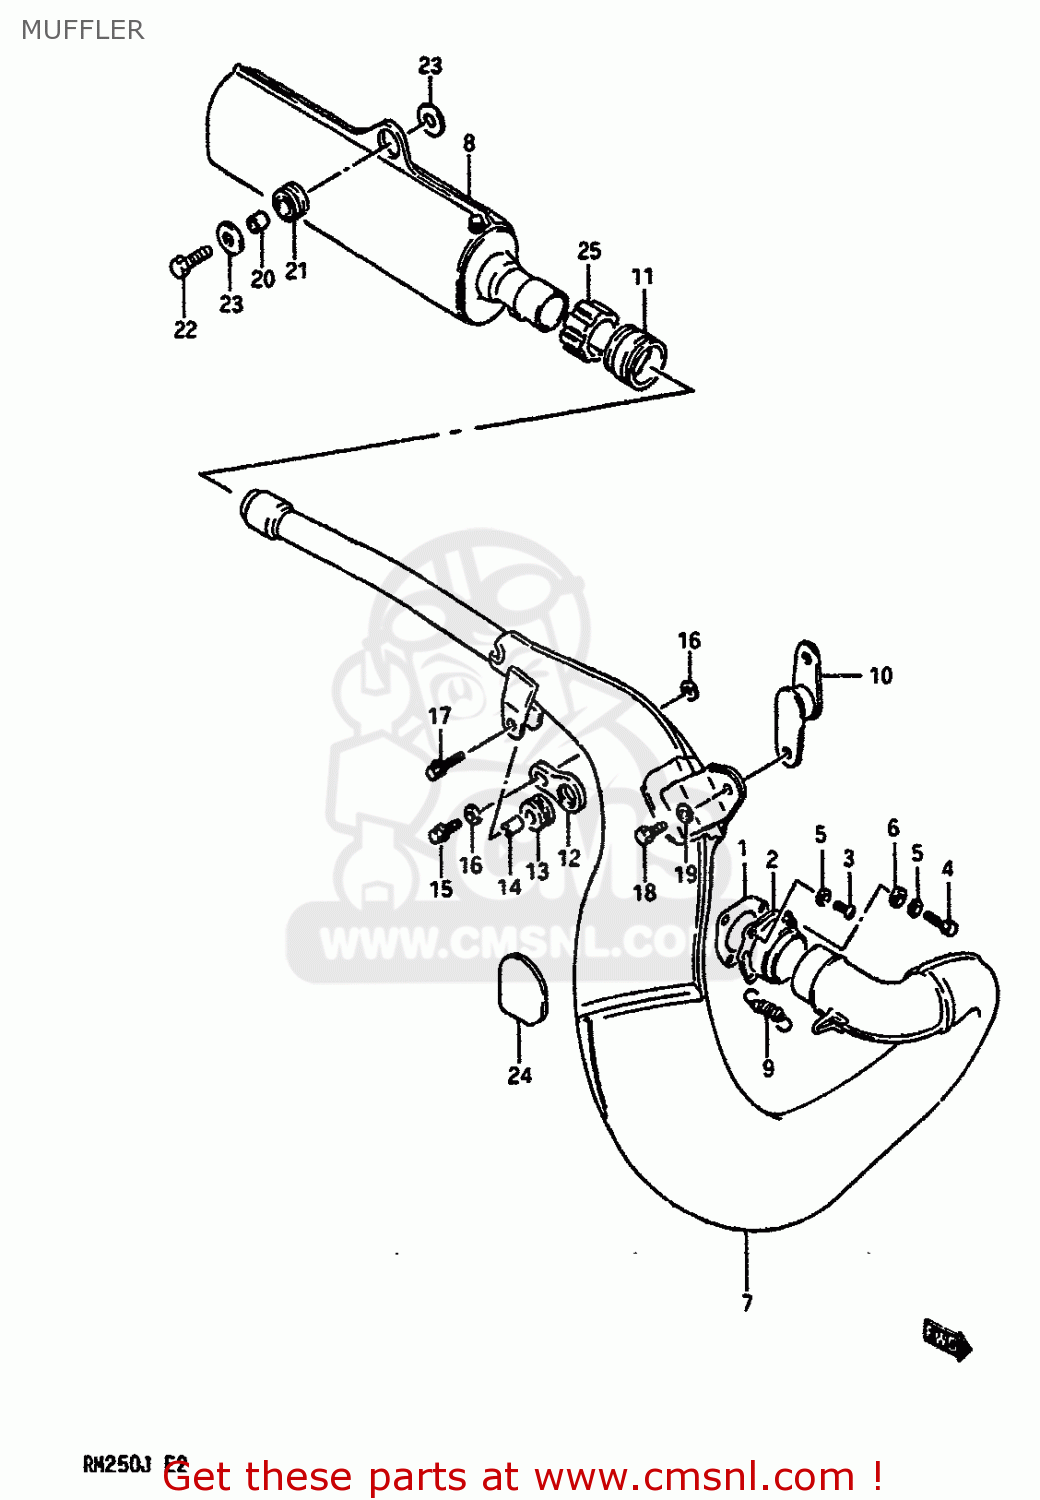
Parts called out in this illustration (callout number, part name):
1	GASKET,EXHAUST PIPE (MCA)
2	FLANGE,EXHAUST PIPE
3	SCREW
4	BOLT(6X20)
5	WASHER,LOCK
6	WASHER(6X10X2)
7	MUFFLER,1ST
8	MUFFLER,2ND
9	SPRING
10	DAMPER,MUFFLER SUPPORT
11	CONNECTOR,MUFFLER
12	PLATE,MUFFLER MTG
13	CUSHION,MUFFLER
14	SPACER (6.4X9X13.5)
15	BOLT
16	WASHER (6.5X20X1.2)
17	BOLT
18	BOLT,8X16
19	LOCK WASHER
20	SPACER (8.8X12X11)
21	CUSHION
22	BOLT
23	WASHER (8.1X33X1.6)
24	CUSHION,SPACER
25	CUSHION
